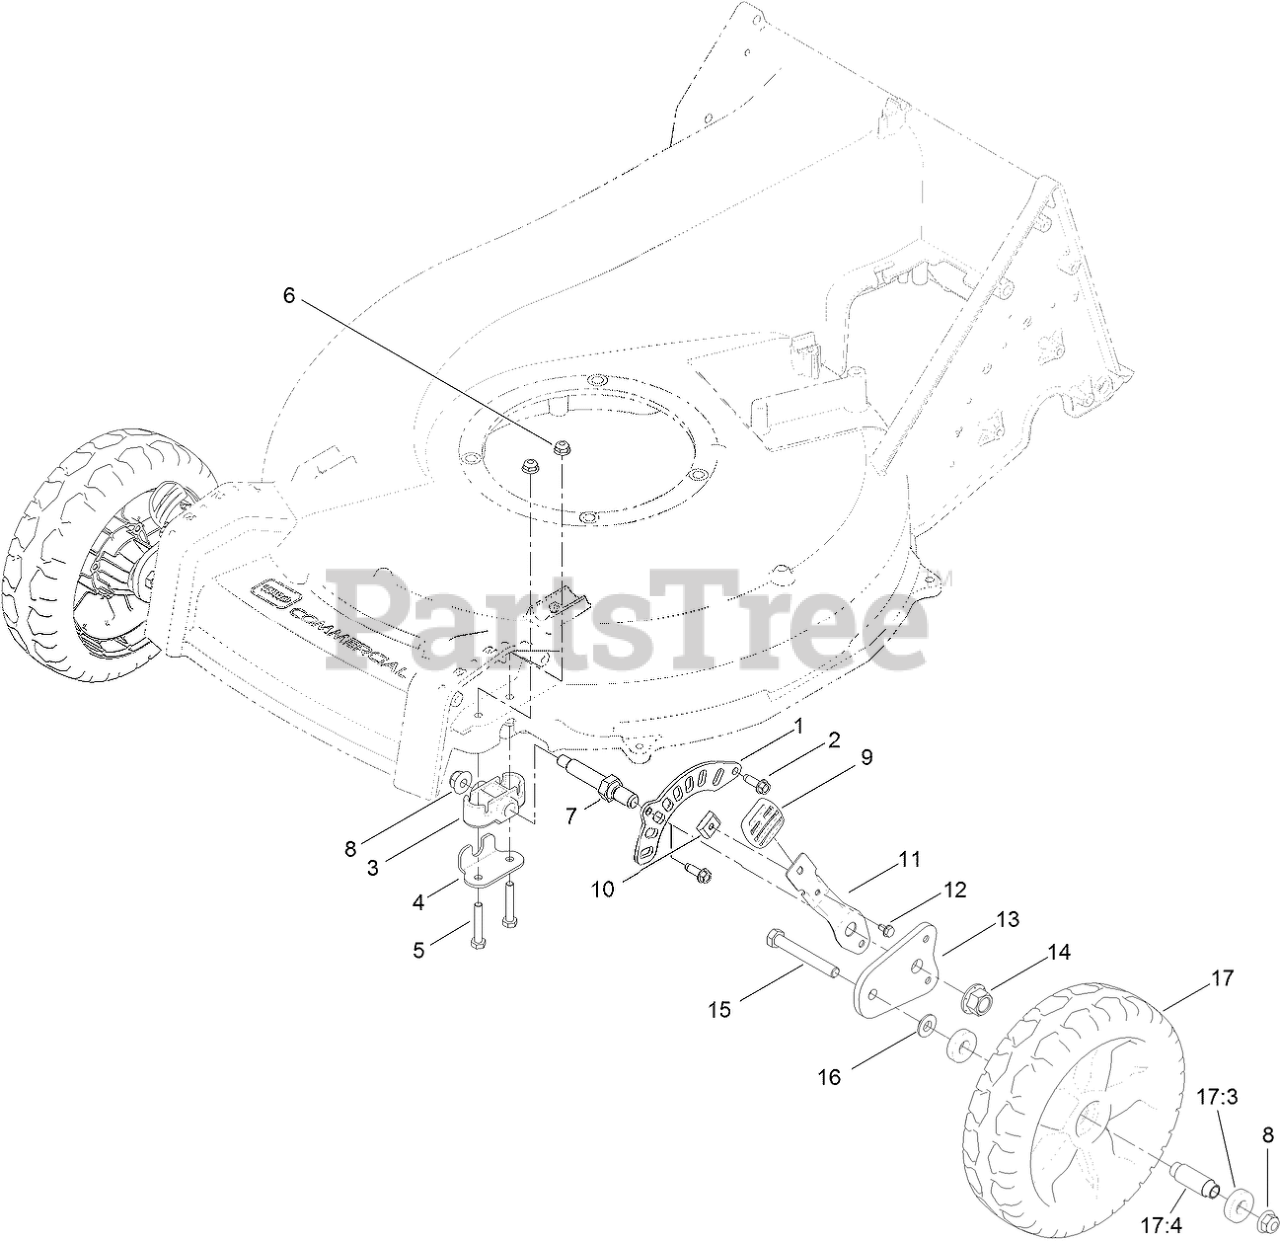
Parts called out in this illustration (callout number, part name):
1	PLATE-HOC, FRONT
2	SCREW-HWHTF
3	BUSHING-AXLE, FRONT HOC
4	RETAINER-BUSHING, FRONT AXLE
5	SCREW-HH
6	NUT-HF
7	AXLE-WHEEL
8	NUT-HF, NI
9	KNOB-LEVER, HOC
10	KEY-ARM, SPRING
11	ARM-SPRING
12	SCREW-HWH
13	ARM-PIVOT, FRONT
14	NUT-LOCK
15	SCREW-HH
16	SPACER-COVER, WHEEL
17	WHEEL
17:3	BEARING-WHEEL
17:4	SPACER
